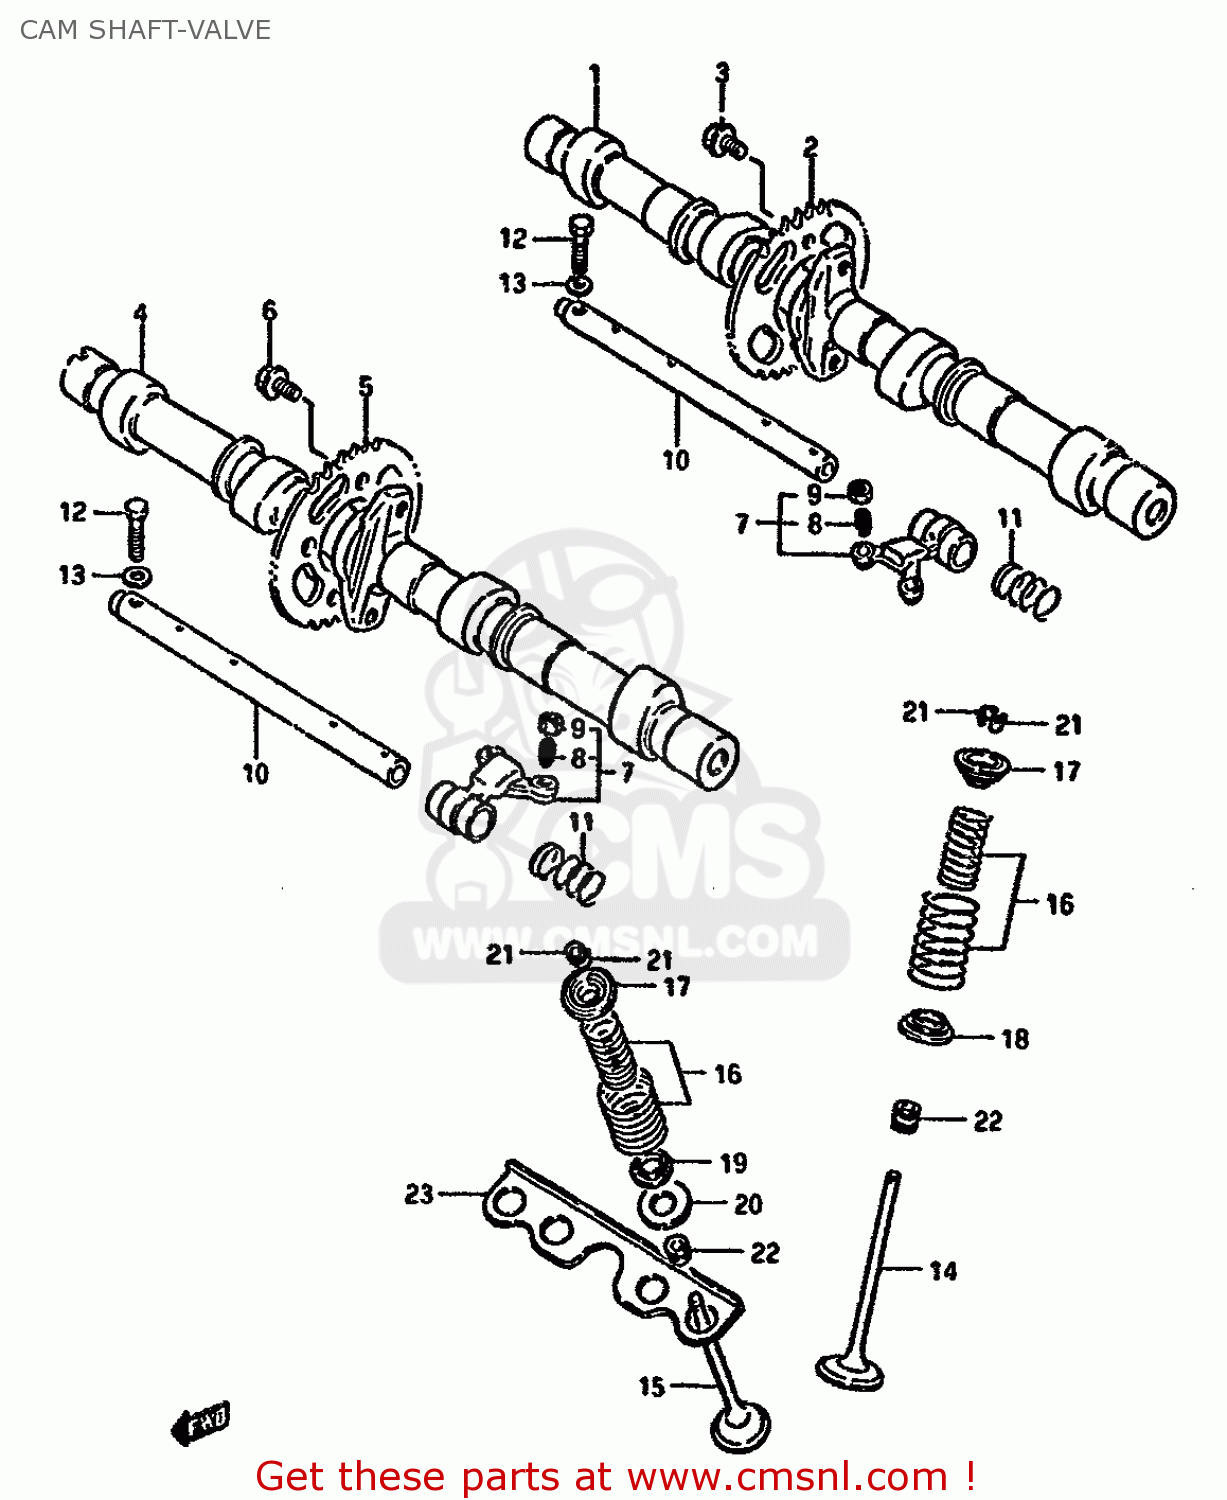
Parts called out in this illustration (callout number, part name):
1	CAMSHAFT,INTAKE
2	SPROCKET,CAMSHAFT
3	BOLT(7X11)
4	CAMSHAFT,EXHAUST
5	SPROCKET,CAMSHAFT
6	BOLT(7X11)
7	ARM,VALVE ROCKER
8	SCREW,TAPPET ADJUSTING
9	NUT,ADJUSTING
10	SHAFT,VALVE ROCKER ARM
11	SPRING
12	BOLT
13	WASHER
14	VALVE,INTAKE
15	VALVE,EXHAUST
16	SPRING SET,VALVE
17	RETAINER,VALVE SPRING
18	SEAT,VALVE SPRING
19	SEAT,VALVE SPRING
20	SEAT,VALVE SPRING EXH OUTER
21	COTTER VALVE
22	SEAL,OIL(5X10X9.7)
23	PLATE
